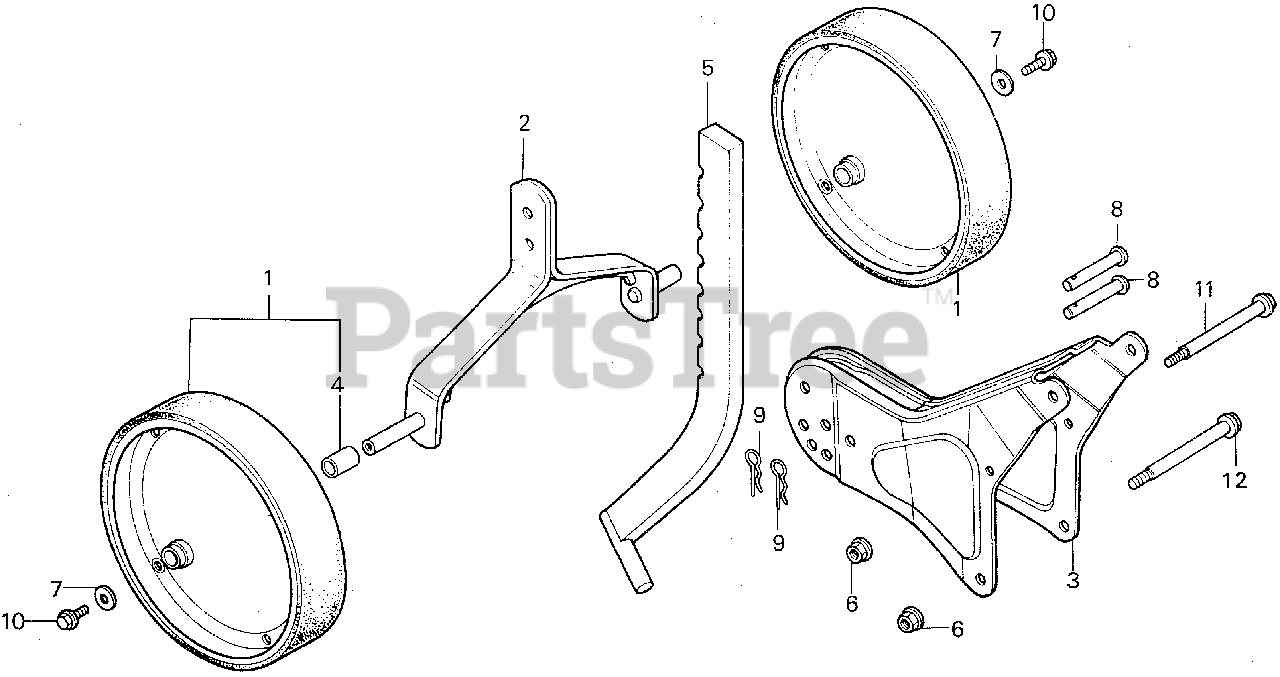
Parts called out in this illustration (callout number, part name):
1	WHEEL, RR.
2	FRAME, RR. WHEEL (NOT AVAILABLE)
3	BOX, HITCH (NOT AVAILABLE)
4	BUSH, TENSIONER ARM
5	BAR, DRAG (NOT AVAILABLE)
6	NUT, FLANGE (8MM)
7	WASHER (6.5X20)
8	PIN (10X53.5)
9	PIN, LOCK (10MM)
10	BOLT, FLANGE (6X12)
11	BOLT, FLANGE (8X80)
12	BOLT, FLANGE (8X80)
